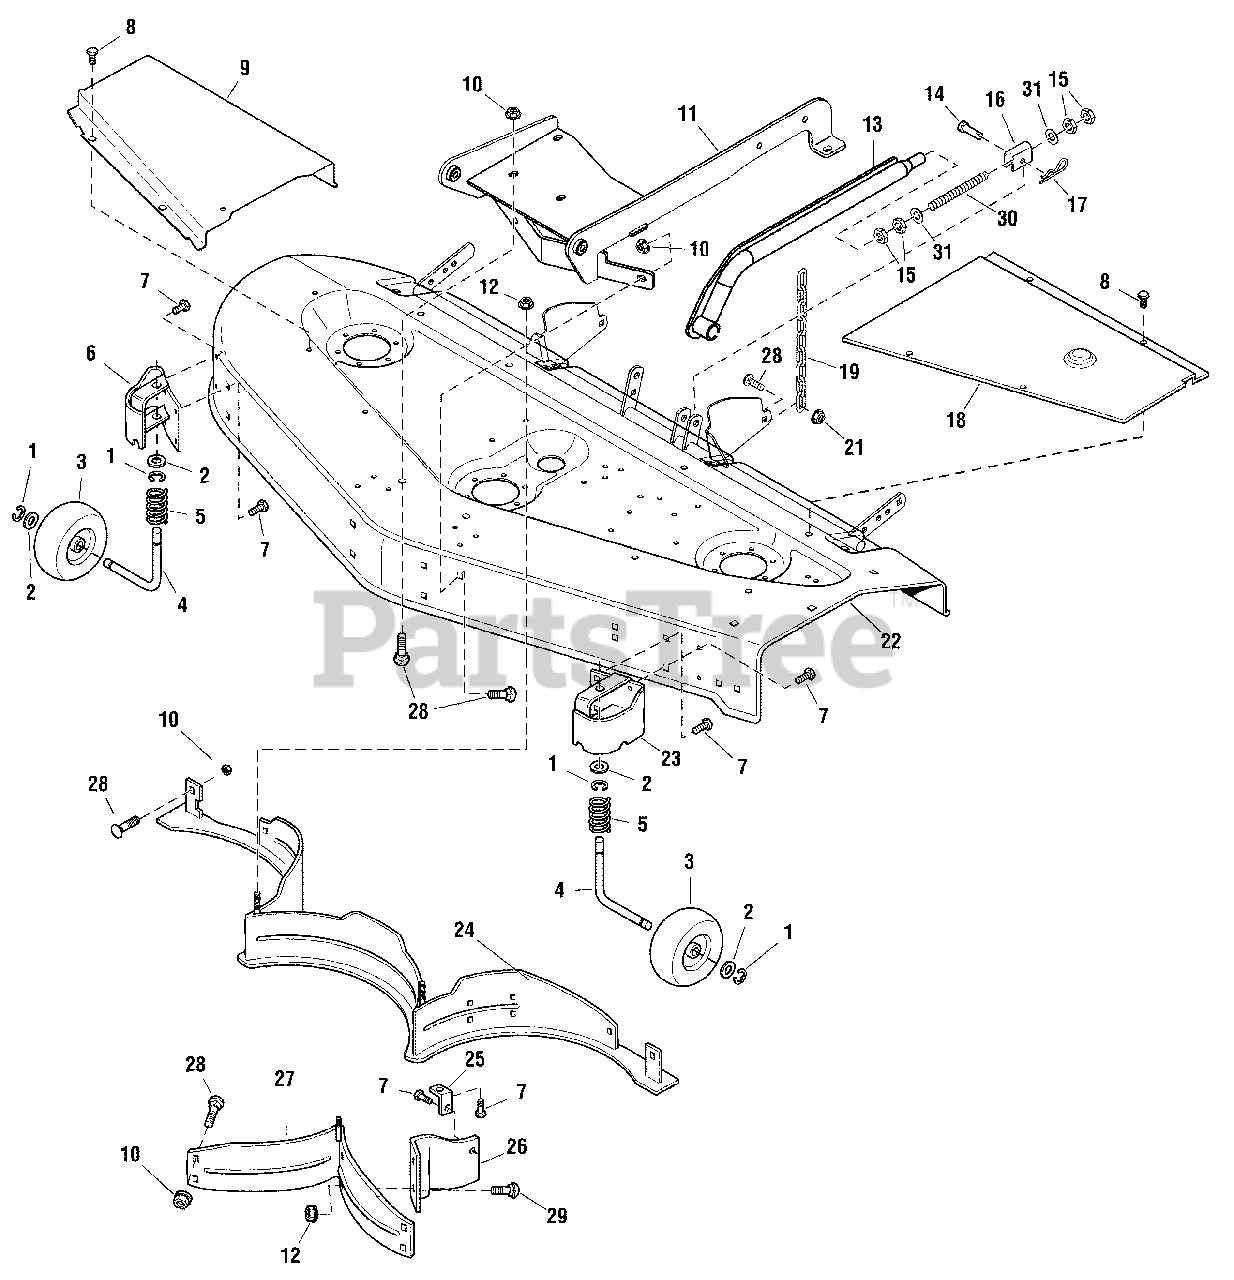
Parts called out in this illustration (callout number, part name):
1	RING, Kipring, External, 1/2
2	WASHER, 5/8
4	SPINDLE
5	SPRING, Comppression
6	BRACKET & YOKE ASSEMBLY
7	CAPSCREW, Hex, Washer Head, Taptite, 5/16-18 x 5/8, Black
8	CAPSCREW, Hex, Washer Head, Taptite, 1/4-20 x 3/8
9	COVER, RH, Orange
9	COVER, RH, Red
10	NUT, Hex, KEPS, 3/8-16, Black
11	HITCH ASSEMBLY
12	NUT, Hex, KEPS, 5/16-18, Black
13	ARM & TUBE ASSEMBLY
14	PIN, Yoke, Drilled, 1/2 x 2, Black
15	NUT, Hex Jam, 5/8-18, Black
16	TRUNION
17	CLIP, Hair Pin, Black
18	COVER, LH, Orange
18	COVER, LH, Red
19	CHAIN, 9 Link
21	NUT, Hex, Flange Lock ESNA, 3/8-16, Black
22	HOUSING, 60", Orange
22	HOUSING, 60", Red
23	BRACKET & YOKE ASSEMBLY
24	BAFFLE & COVERS ASSEMBLY
25	BRACKET
26	BAFFLE, Discharge
27	BAFFLE & ROD ASSEMBLY
28	CARRIAGE BOLT, 3/8-16 x 1, Black
29	CARRIAGE BOLT-RD, 5/16-18 x 3/4, Black
30	STUD, 5/8-18 x 8-9/16
31	WASHER, Plain 5/8
